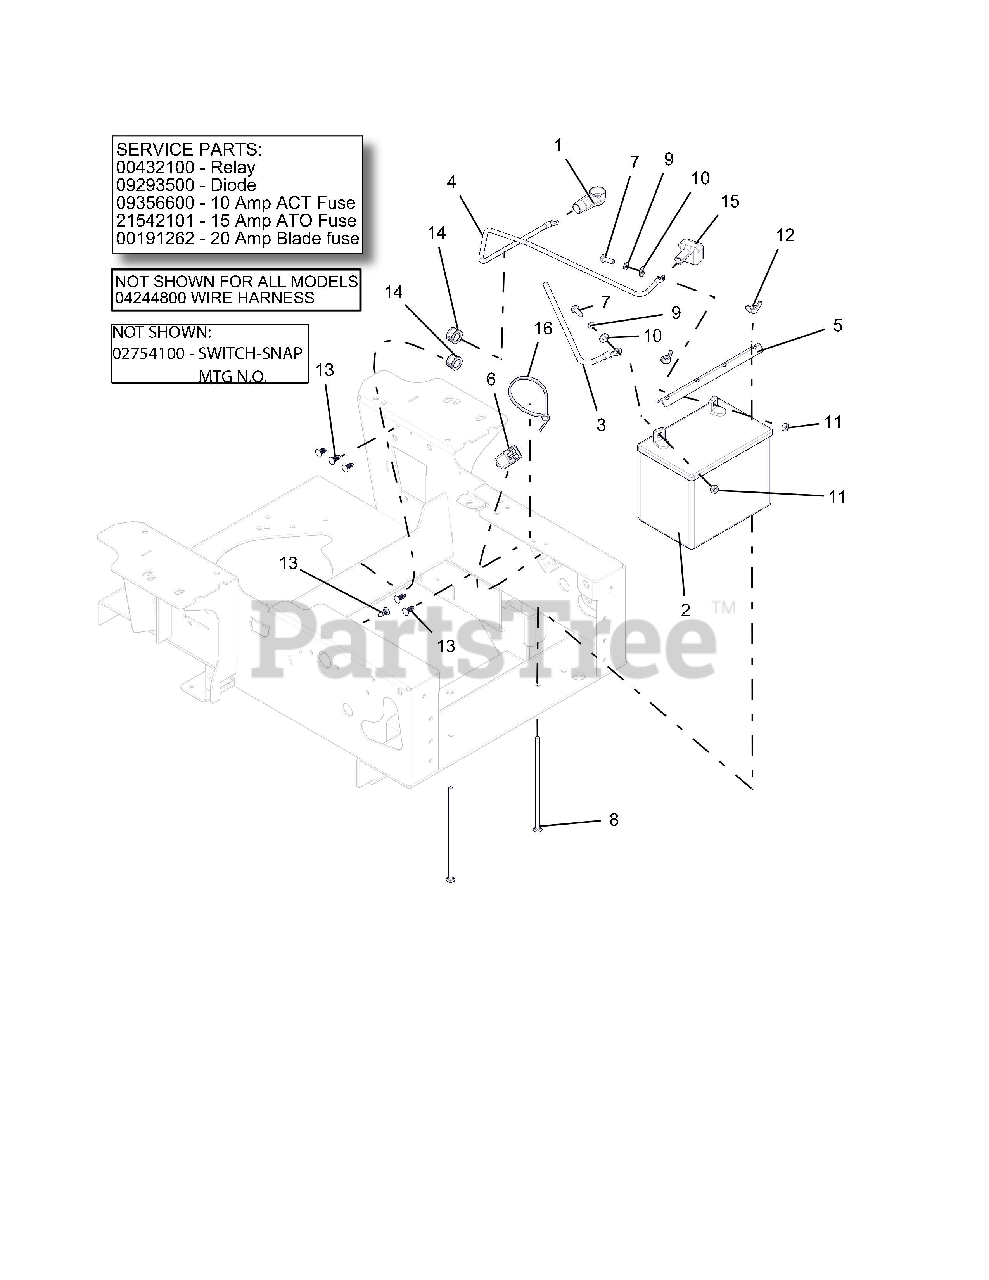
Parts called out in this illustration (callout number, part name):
1	BOOT, .65 ID POS
2	BATTERY, 300 CCA 10U1L
3	CABLE, GROUND 22.00"
4	CABLE, STARTER .31 X 23.00 X .31
5	HOLD DOWN - BLK
6	SWITCH, SNAP IN -N.O./N.O
7	BLT-HEX .25-20X.75 GR5 YWZC
8	BLT-RDHDSQNK .25-20X7.50 G2 YWZC
9	WSHR-LK .25X.062 REG YWZC
10	WSHR-FL-STL.281X.62X.065 YWZC
11	NUT-HEX .25-20 YWZC
12	NUT-LOCKING WING 1/4-20
13	RIVET, .25 NYLON PANEL
14	BUSH, PANEL SNAP .687X.875X.56
15	INSULATOR
16	CABLE, TIE 5.50 LG
17	RELAY
18	DIODE
19	10 AMP ACT FUSE
20	15 AMP ATO FUSE
21	20 AMP BLADE FUSE
22	WIRE HARNESS
23	SWITCH - SNAP MTG N.O.
